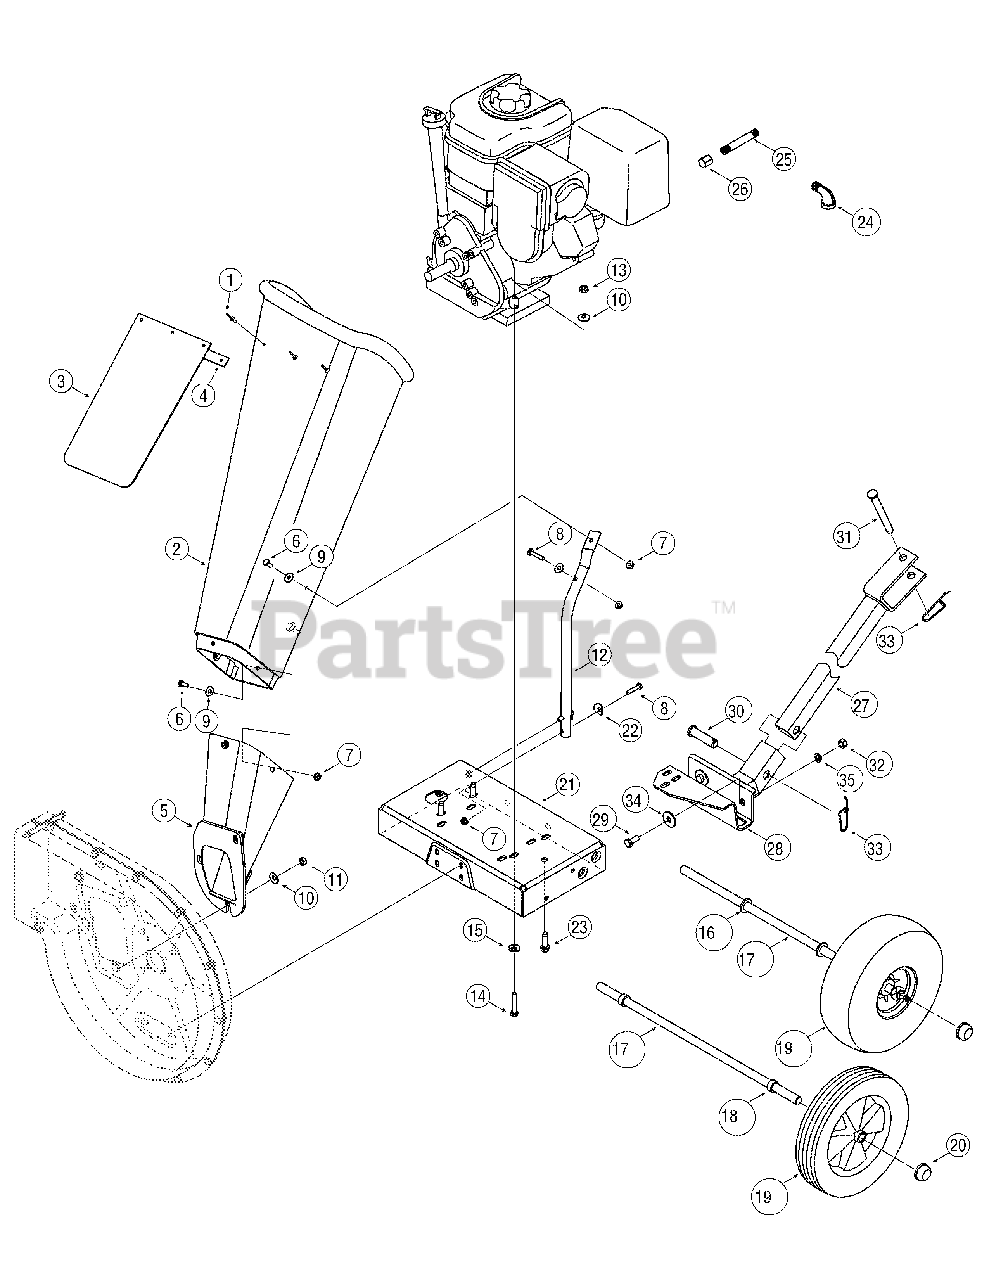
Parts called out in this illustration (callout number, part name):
1	Pop Rivet
2	Chipper Shredder Chute
3	Chute Flap
4	Chute Flap Strip
7	Hex Lock Nut 1/4-20
8	Hex Cap Screw 1/4-20 x 1.25
9	Flat Washer.28 ID x.74 OD
10	Bell Washer.340 ID x.872 OD
11	Hex Nut 5/16-18
13	Hex Lock Nut 5/16-18
14	Hex Cap Screw 5/16-18 x 1.50
14	Hex Cap Screw 5/16-18 x 1.75
15	Bell Washer 5/16 x 1.0
16	Flat Washer
17	Axle Assembly
18	Spacer
19	Wheel Comp., 10.0 x 2.5 Plastic
19	Wheel Complete, 10.0 x 4.0 Gray
20	Push Cap
22	Washer,.320 ID x.93 OD
23	Screw, 3/8-16 x 1.250
24	Elbow Fitting
25	Oil Drain Pipe
26	Oil Drain End Cap
29	Hex Cap Screw, 3/8-16 x.88
30	Clevis Pin,.625 x 2.4
31	Clevis Pin,.50 x 4.62
32	Hex Nut, 3/8-16
33	Spring Pin
34	Flat Washer,.411 x 1.25 x 1.0
35	Lock Washer, 3/8
